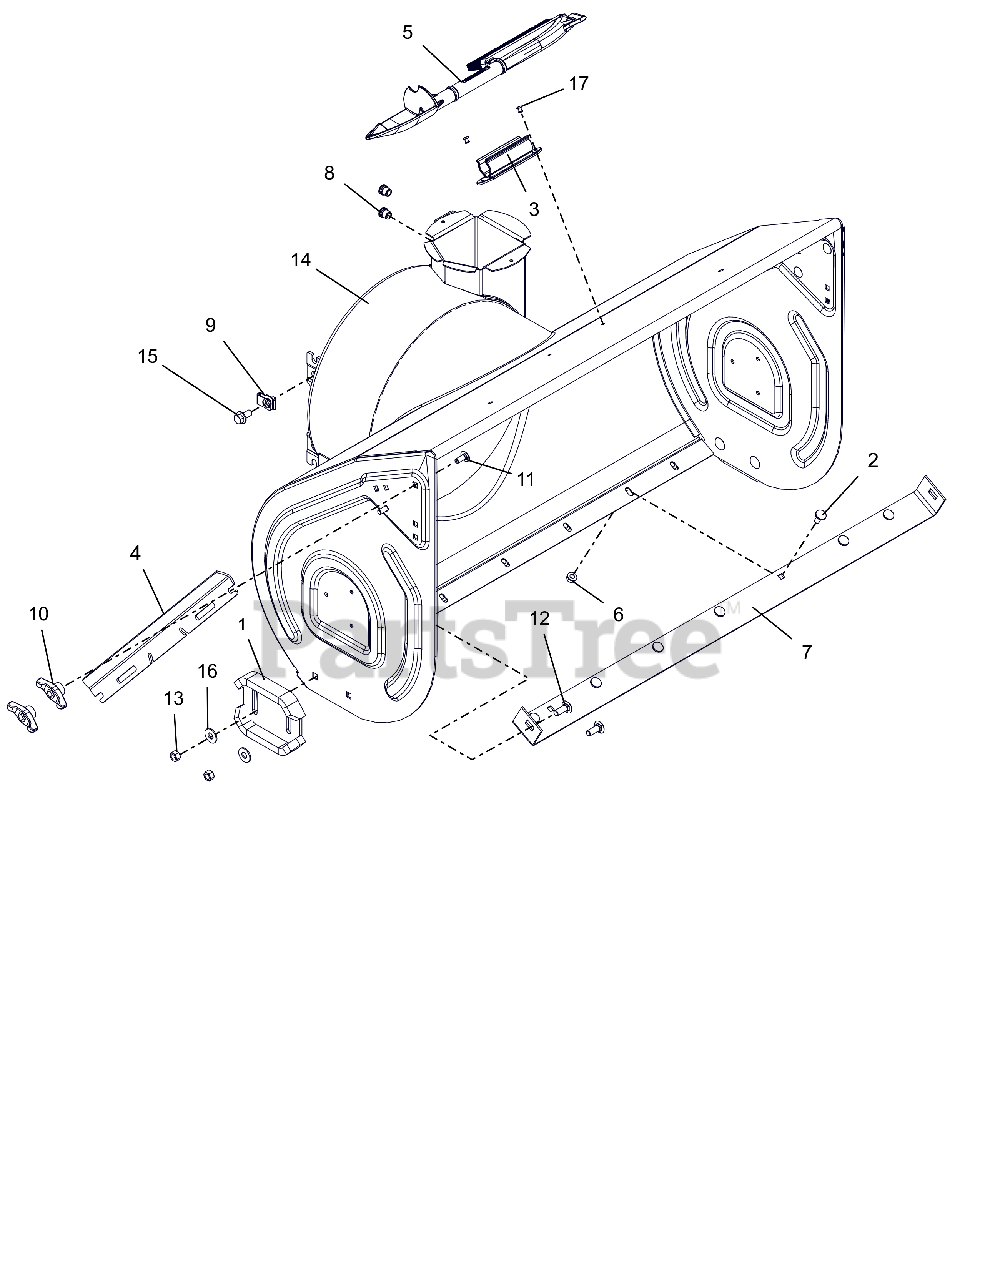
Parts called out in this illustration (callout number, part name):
1	RUNNER, SKID SHOE
2	BOLT, MODIFIED HEAD CARRIAGE
3	MOUNT, SNOW CLEAN OUT
4	CUTTER, DRIFT
5	DEVICE, SNOW CLEAN OUT W/BRUSH
6	NUT-LK-TOP-FLG .312-18 GF ZCC
7	BLADE, SCRAPER-36"
8	NUT,THD,INSERT .38-16 ZC120
9	NUT-RTNR .375-16X.37
10	KNOB,WING .31-18 UNC NYL/TALC
11	BLT, RHSSN.31-18X.750 G5 ZCC
12	BLT,RHSSN .38-16X1.00 G5 ZCC
13	NUT-LK-CTR .38-16 ZC120
14	BLOWER HOUSING W/DECAL 36"
16	WSHR,FLT .438X1.00X.083 ZCC
17	RVT, POP .1875 ZCC
